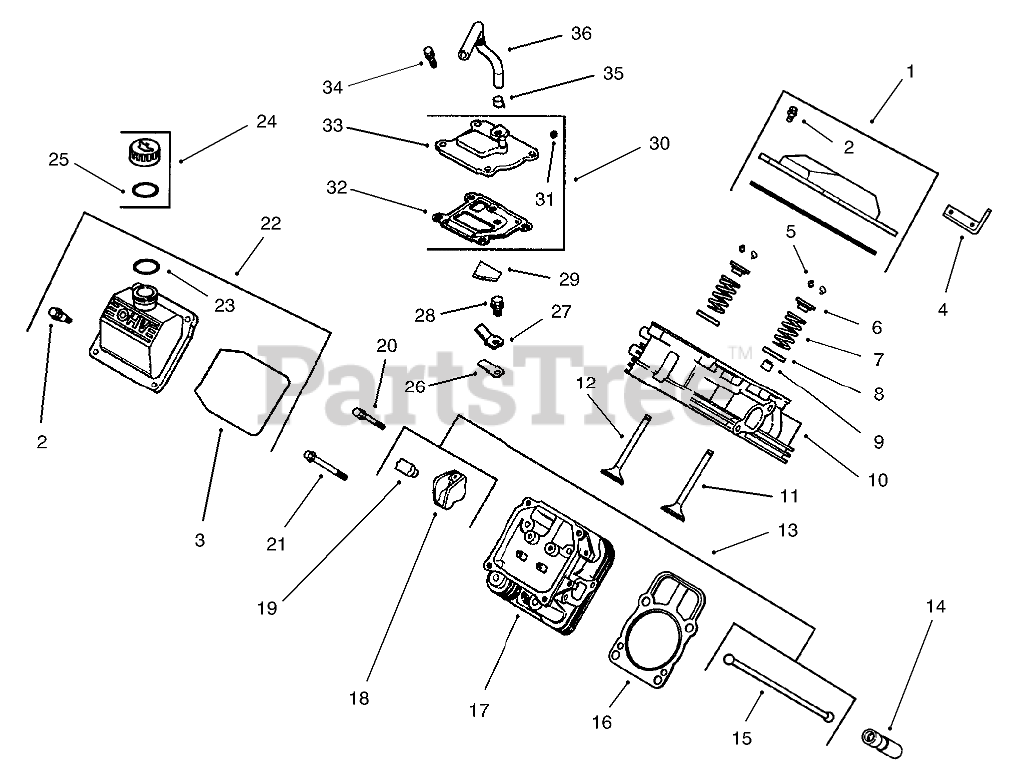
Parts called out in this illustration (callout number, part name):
1	Kit, valve cover-plain (Includes 2-3)
2	Screw
3	O-Ring
4	Strap-Lifting
5	Retainer Kit
6	Cap-Spring, Valve
7	Spring-Valve
8	Retainer-Spring
9	Seal-Stem, Valve
10	Head Asm-#1 Cylinder
11	Valve-Intake
12	Valve-Exhaust
13	Kit, valve train (Includes 15, 18, 19)
14	Lifter-Valve
15	Rod-Push
16	Gasket-Cylinder Head
17	Head Asm-#2 cylinder
18	Arm-Rocker
19	Pivot-Arm, Rocker
20	Screw
21	Screw
22	Kit, valve cover-oil fill (Includes 2, 3, 23)
23	O-Ring
24	Kit, oil fill cap (Includes 25)
25	"O"Ring
26	Reed
27	Retainer-Reed
28	Screw
29	Filter-Breather
30	Kit, breather (Includes 31-33)
31	Plug
32	Gasket-Breather
33	Cover-Breather
34	Screw
35	Clamp
36	Hose-Breather
